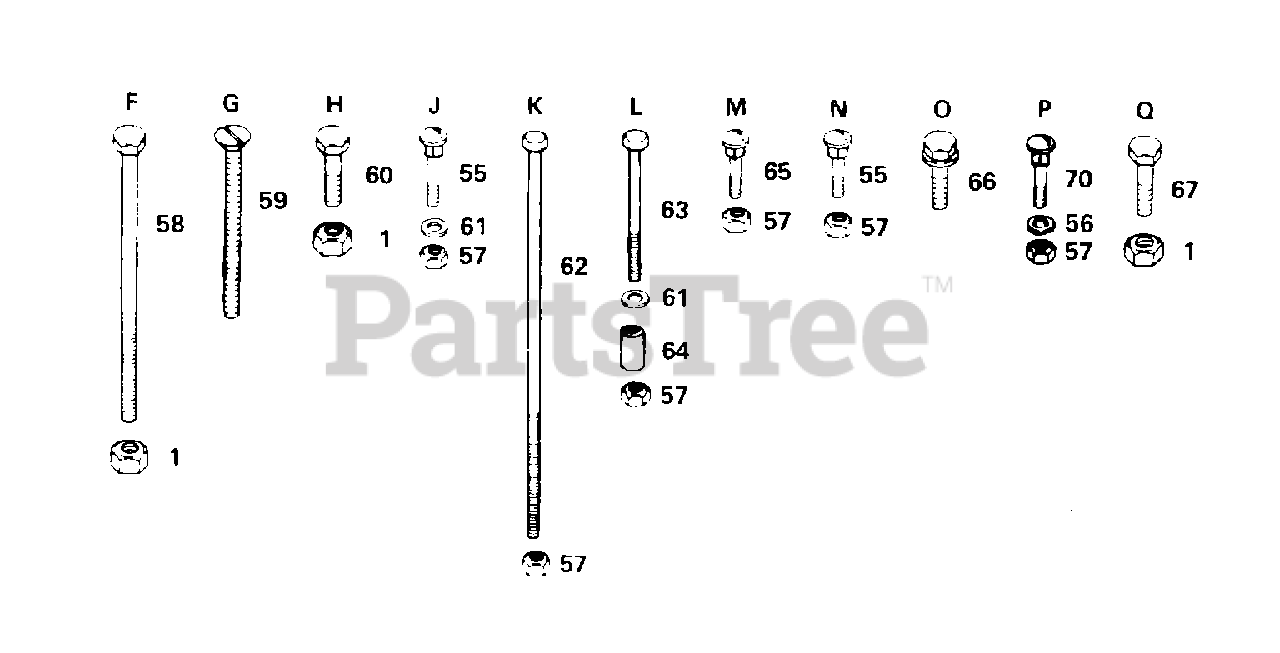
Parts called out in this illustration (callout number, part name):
55	BOLT
56	WASHER
58	BOLT - HEX 3/8 - 16 X 3
59	SCREW YT
61	WASHER M
62	BOLT
63	BOLT.HEX.5/16-1.5
64	SPLIT SPACER RT
65	BOLT
66	SCREW
67	BOLT
